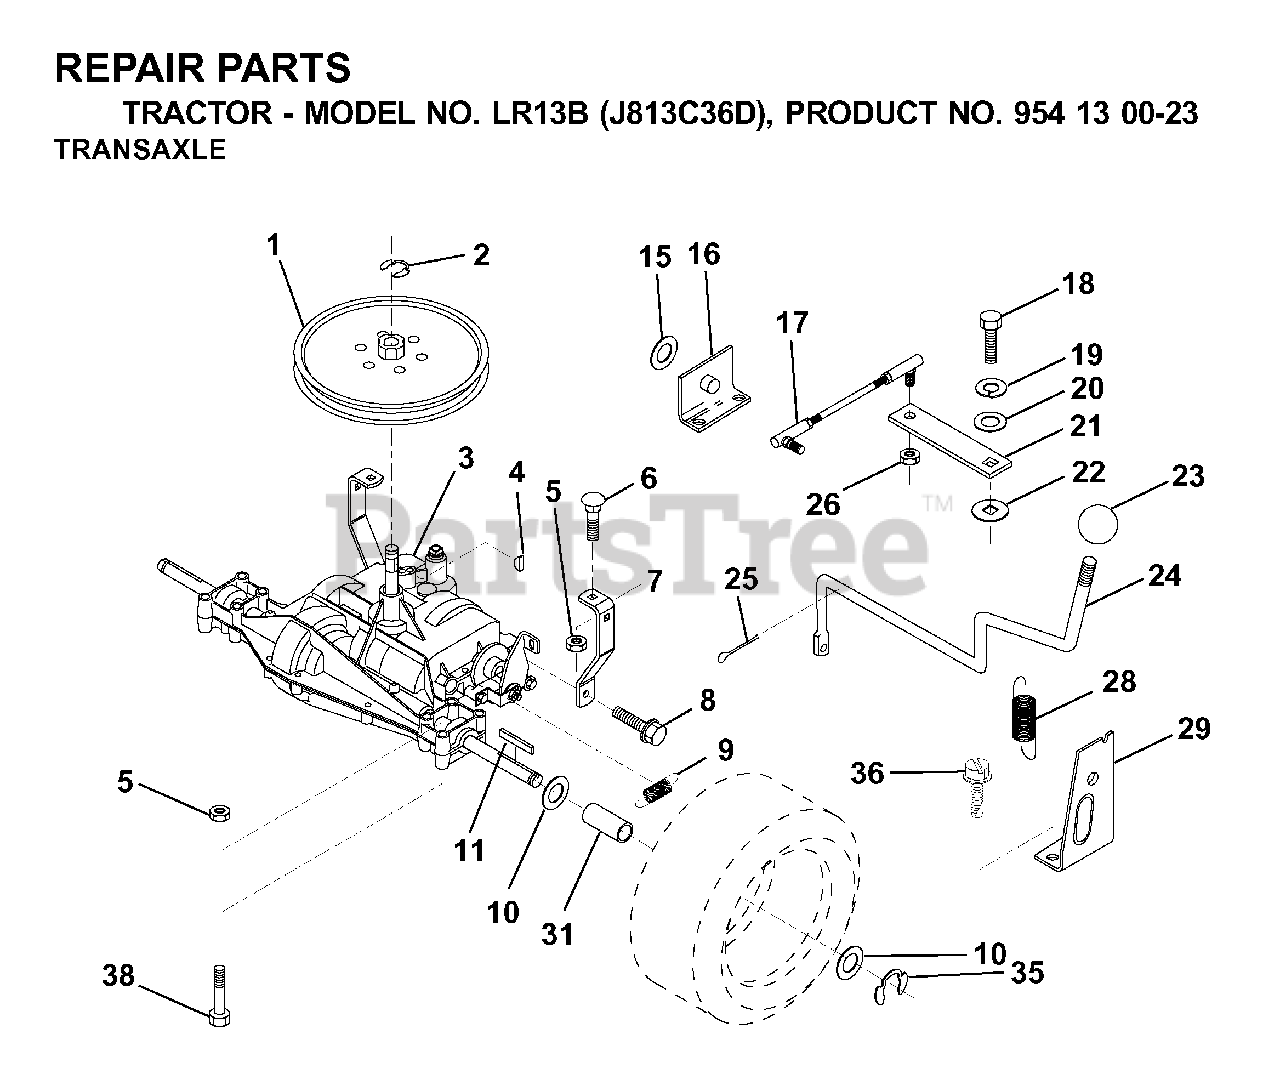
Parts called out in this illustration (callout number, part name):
2	RETAINING RING LT
5	LOCKNUT
6	BOLT
7	STRAP,TORQUE
8	SCREW 5/16"
9	SPRING,BRAKE RETURN
11	SQUARE KEY
15	WASHER
16	SUPT, HDLE SHT LH
18	BOLT 1/4-28X3/4
19	LOCKWASHER
20	WASHER LT
22	WASH-SHFT PLT LT
23	KNOB.DUCKHEAD.1/2
24	ROD, SHIFT
25	PIN COTTER
26	LOCKNUT
28	SPRING.EXTENSION
29	SUPPORT HANDLE SHAFT RH
31	SPACER AXLE
35	E-RING LT
36	SCREW
38	BOLT
